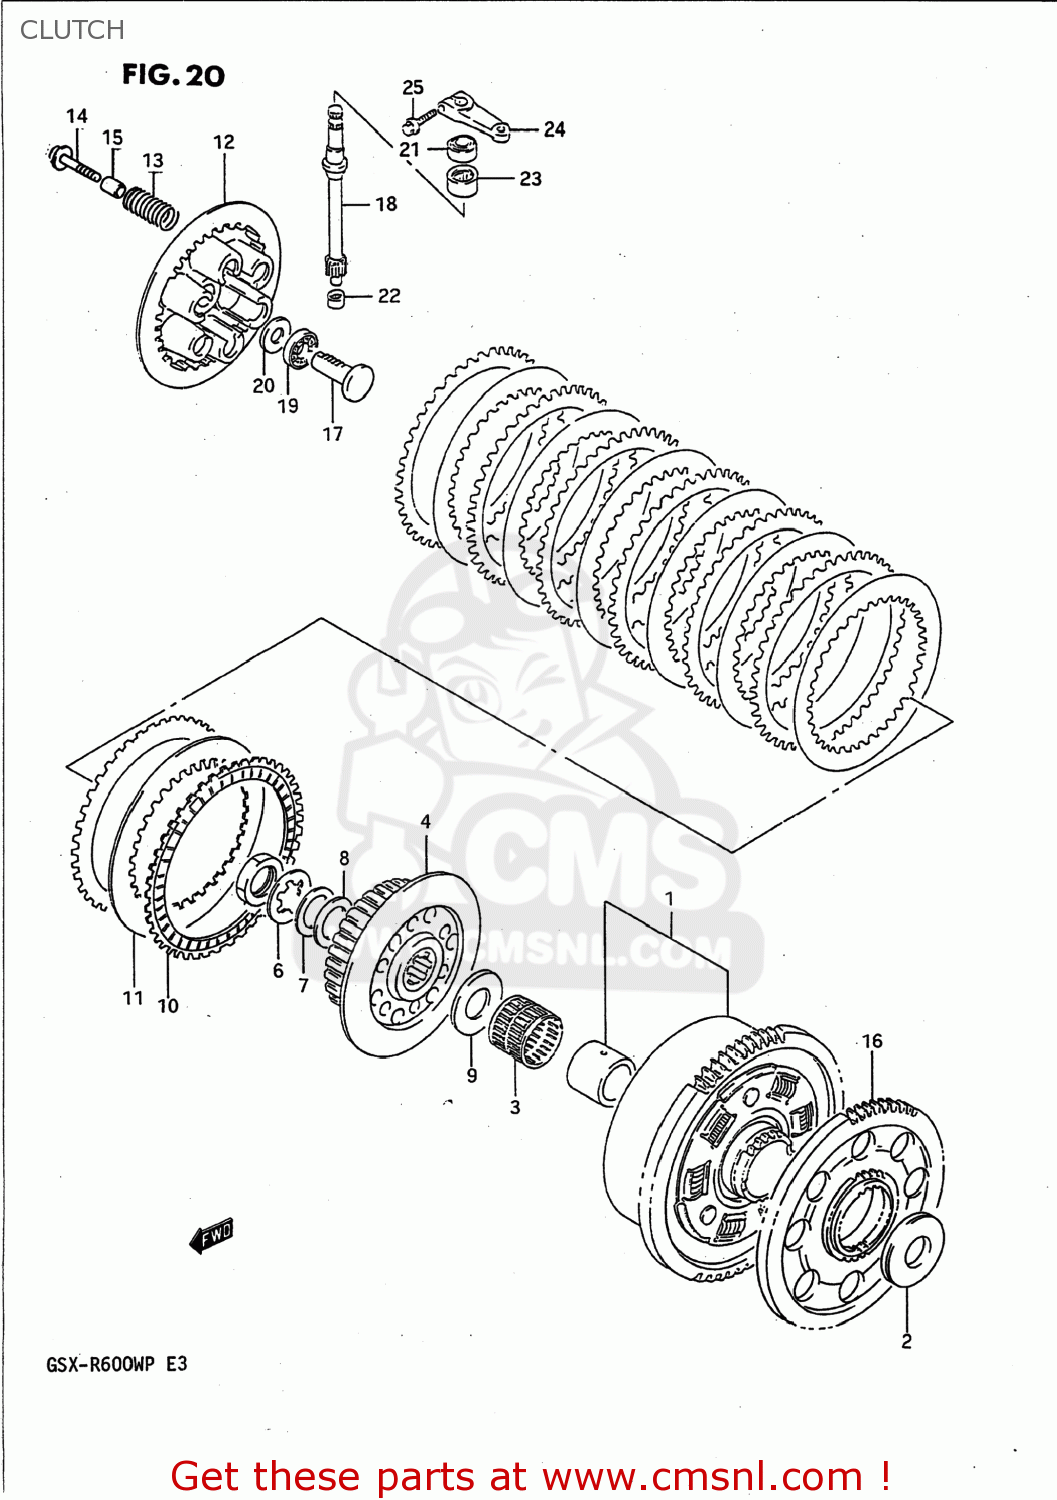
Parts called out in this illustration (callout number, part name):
1	GEAR ASSY,PRI DRIVEN
2	WASHER(25X54X2.5)
3	BEARING(35X40X35.8)
4	HUB,CLUTCH SLEEVE
5	NUT
6	WASHER,LOCK
7	WASHER
8	WASHER
9	WASHER(25X50X2.5)
10	PLATE,CLUTCH DRIVE
11	PLATE,CLUTCH DRIVEN
12	DISC,CLUTCH PRESSURE
13	SPRING
14	BOLT
15	SPACER
16	GEAR,GENERATOR DRIVE
17	RACK,CLUTCH RELEASE
18	PINION,CLUTCH RELEASE
19	BEARING(15X28X2)
20	WASHER
21	OIL SEAL
22	BEARING 10X14X10
23	BEARING(15X22X12)
24	ARM,CLUTCH RELEASE
25	BOLT
